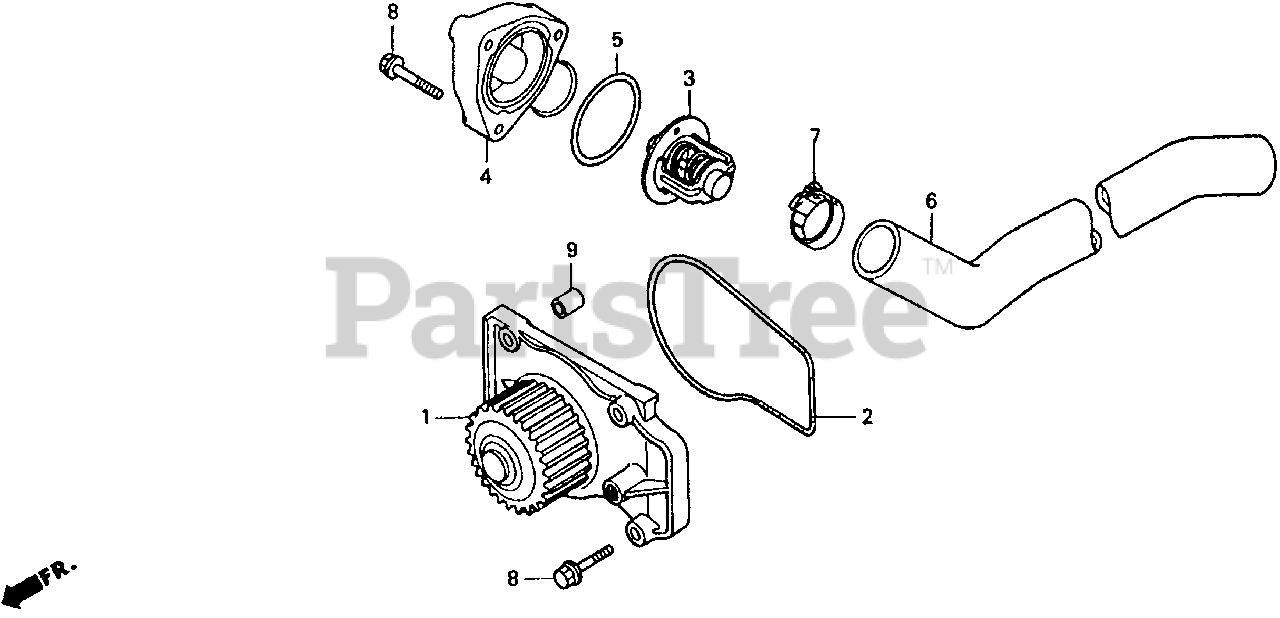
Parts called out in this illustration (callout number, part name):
1	WATER PUMP
2	O-RING, WATER PUMP
3	THERMOSTAT
4	COVER, THERMOSTAT
5	O-RING, THERMOSTAT COVER
6	HOSE B, WATER (LOWER)
6	HOSE B, WATER
7	BAND, WATER HOSE
8	BOLT, FLANGE (6X32)
9	PIN A, DOWEL (8X14)
